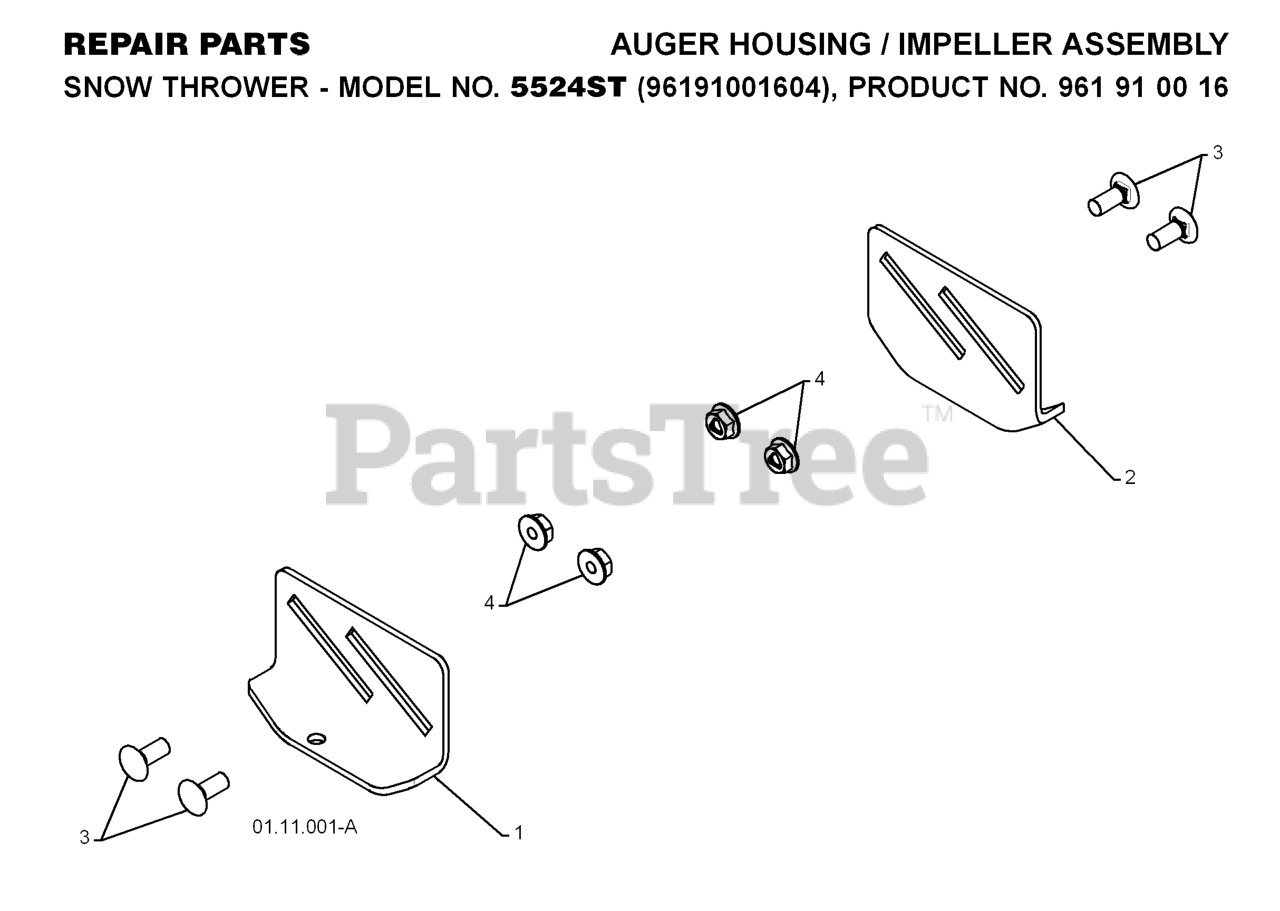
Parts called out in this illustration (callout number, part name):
1	SKID PLATE LH
2	SKID PLATE RH
3	BOLT
4	NUT.LOCK.5/16-18
